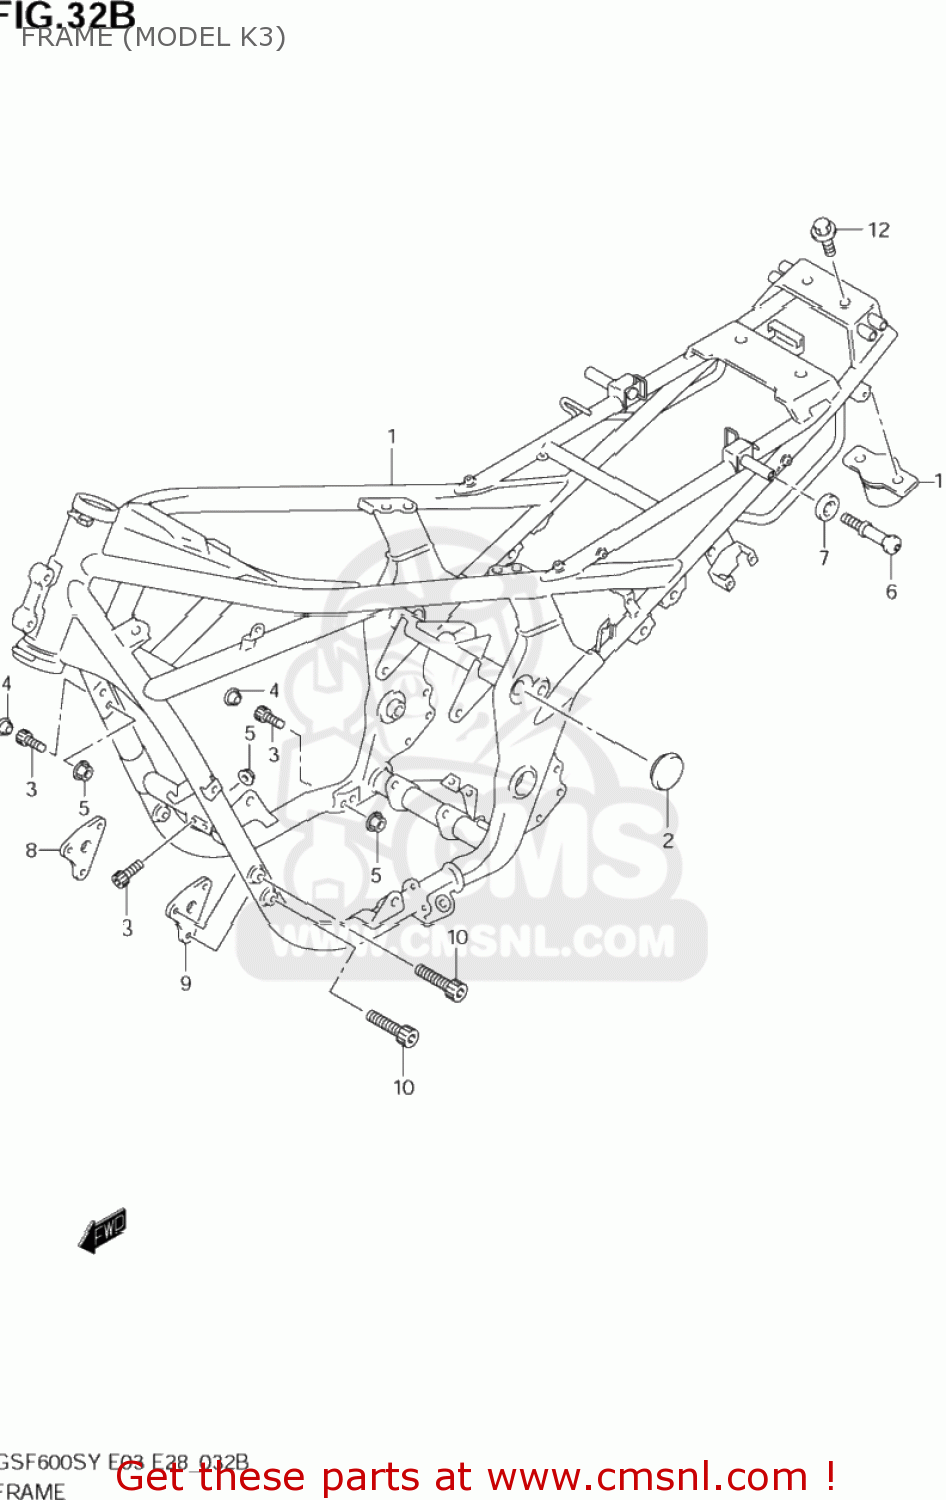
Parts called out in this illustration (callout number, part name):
1	FRAME COMP
2	CAP,FRAME BODY
3	BOLT(10X37)
4	CAP(OD:12)
5	NUT
6	HOOK,SEAT RAIL
7	WASHER,HOOK
8	PLATE,ENG MTG,R
9	PLATE,ENG MTG,L
10	BOLT
11	DAMPER,FRAME RR
12	BOLT
